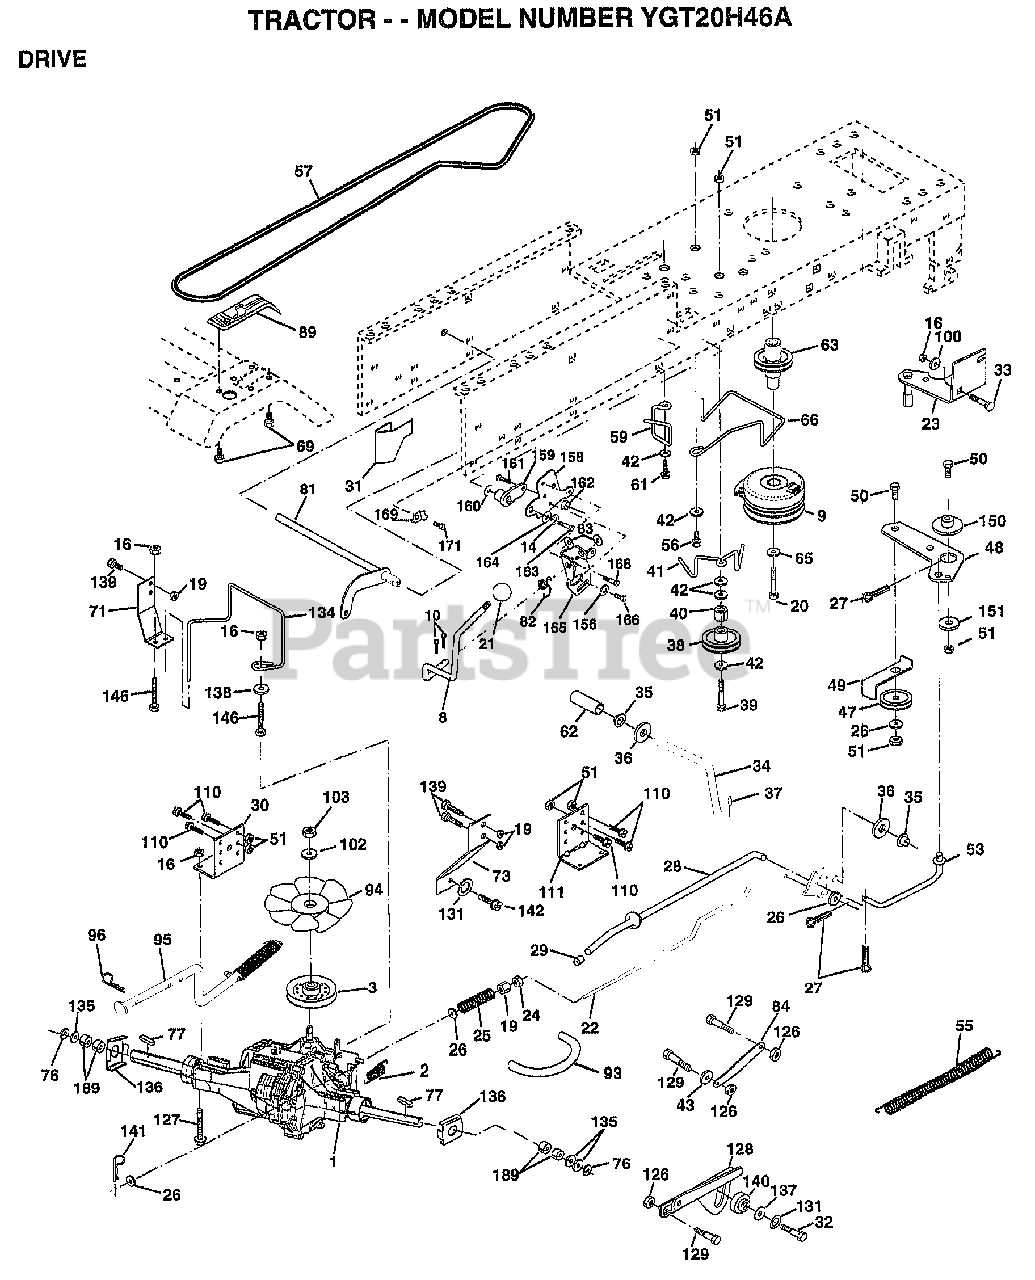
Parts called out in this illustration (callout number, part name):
2	SPRING RET BRAKE
3	PULLEY.TRANSAXLE
8	ROD.SHIFT.FEND.ADJ.YT
9	CLUTCH.ELECTRIC
10	PIN COTTER 1/8
14	LOCKWASHER
16	NUT
19	NUT
20	BOLT.7/16-20X4.25
21	KNOB.DUCKHEAD.1/2
22	BRAKE.ROD.HYDRO.
23	DASH-LOWER
24	NUT HEX JAM 3/8-16
25	SPRING ROD LT
26	WASHER
27	COTTER PIN
28	ROD.BRAKE.PARK.LT
29	PLUNGER CAP T
30	BRKT TRANS LH
31	KEEPER BELT LH
32	BOLT
33	BOLT
34	SHAFT ASM-PEDAL F
35	NYLON BEARING
36	WASHER LT
38	FLAT IDLER PULLEY
39	BOLT
40	SPACER T
41	"KEEPER,BELT.IDLER FLAT"
42	WASHER
43	WASHER T
48	BELLCRANK.CLUTCH
49	RETAIN BELT
53	"LINK, CLUTCH T"
55	"SPRING, RETURN LT"
57	BELT.DRIVE
59	KEEPER BELT CNTSP
61	SCREW
62	"COVER,PEDAL"
63	PULLEY.ENGINE.1-1/8
65	LOCKWASHER
66	ENGINE BELT KEEPR
69	SCREW HEXWSH H-L
71	STRAP.TORQUE.LH.HYDRO
73	STRAP.TORQUE.RH.HYDRO
76	E RING HYT
77	SQ KEY STD
81	SHIFT.ASM.CROSS.TAPER
82	"SPRING,TORSION"
83	WASHER
84	TRANSAXLE LINK
89	CONSOLE.SHIFT.AUTO.YT/GT.BLACK
90	NUT
93	"LINE FUEL HYD 4"""
94	"FAN 7"" HYDRO"
95	CONTROL.ASM.BYPAS
96	RETAINER M
100	WASHER M
102	WASHER BELLEVILLE
111	BRKT TRANS RH
127	BOLT.HEX.FLGHD.
128	BRKT NEUTRAL ADJ
134	"KEEPER BELT,RH"
135	WASHER
136	WASHER.AXLE.HYDRO
137	WASHER
138	WASHER
139	BOLT
140	BUSHING.PINION.SECTOR
142	BOLT.5/16X24X1
150	BUSHING.BELLCRANK.GRD.DR
151	WASHER
156	WASHER.SRRTD.5/16
158	BRKT.SHIFT.MOUNT
159	HUB.SHIFT
160	WASHER
161	BOLT T
164	WASHER.5/8X.281X10GA
165	BRKT.PIVOT.LEVER
166	SCREW.5/16-18X5/8
168	BOLT.SHOULDER.5/16-18X.561
169	PLATE.FASTENING
171	SCREW LT
189	WASHER.SPACER AXL
